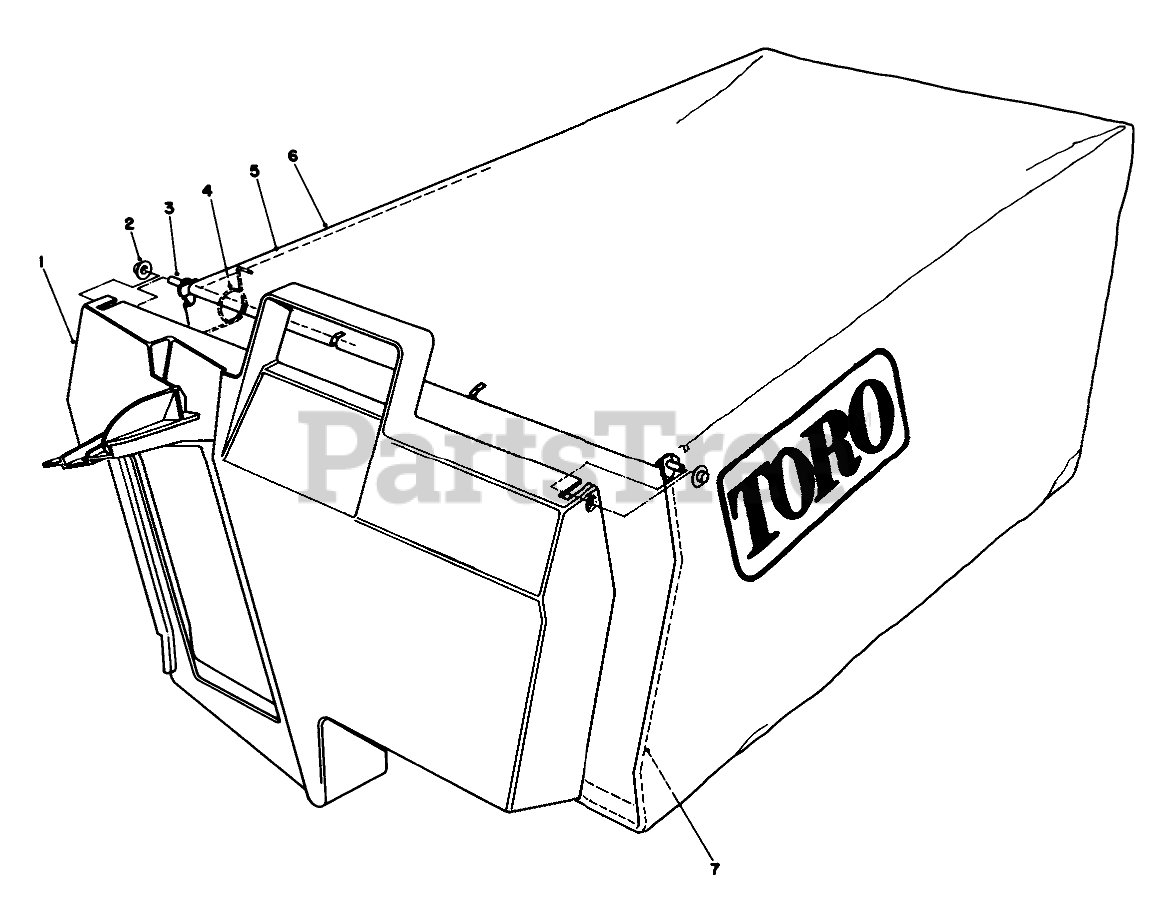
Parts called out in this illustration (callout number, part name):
1	DOOR-BAG, GRASS
2	NUT-PUSH
3	HINGE-DOOR, BAG
4	SPRING
5	FRAME-BAG, UPPER
6	Bag-Grass
7	FRAME-BAG
